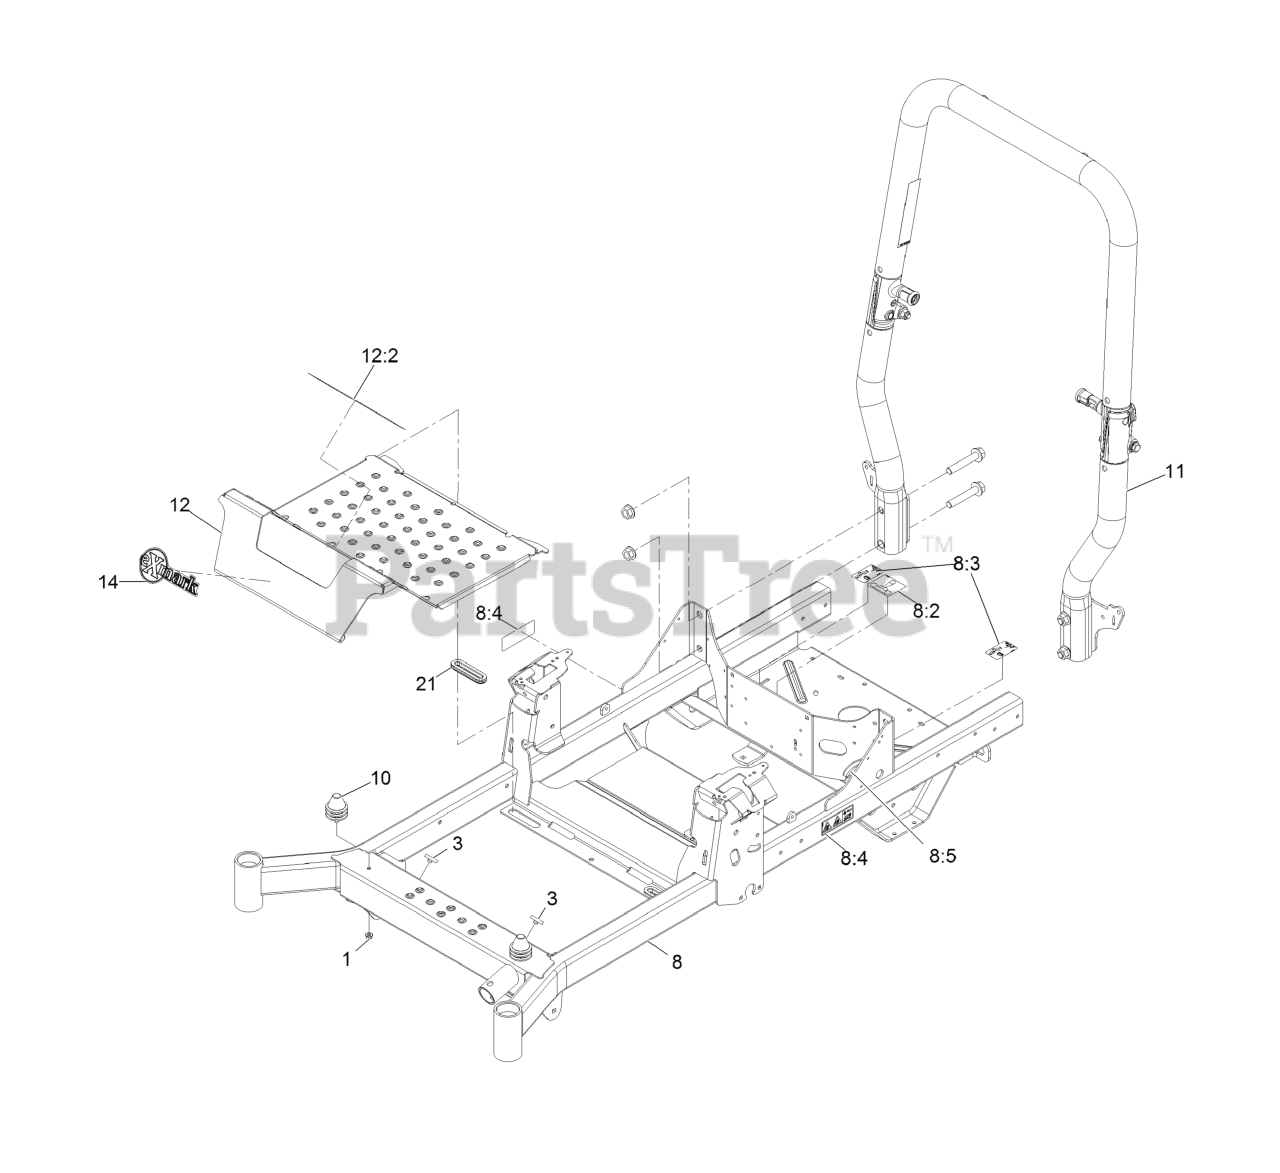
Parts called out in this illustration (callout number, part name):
1	NUT-HF, NI
3	BUMPER-PUSH-IN, RUBBER
8	FRAME ASM
8:2	DECAL-ROUTING, BELT
8:3	DECAL-RELEASE, DRIVE
8:4	DECAL-WARNING
8:5	STRIP-SEAL
10	ISOLATOR
11	ASM-ROPS TAPERED
12	PAN-FLOOR
12:2	DECAL-DANGER
14	DECAL-EXMARK LOGO
21	GROMMET-RUBBER
